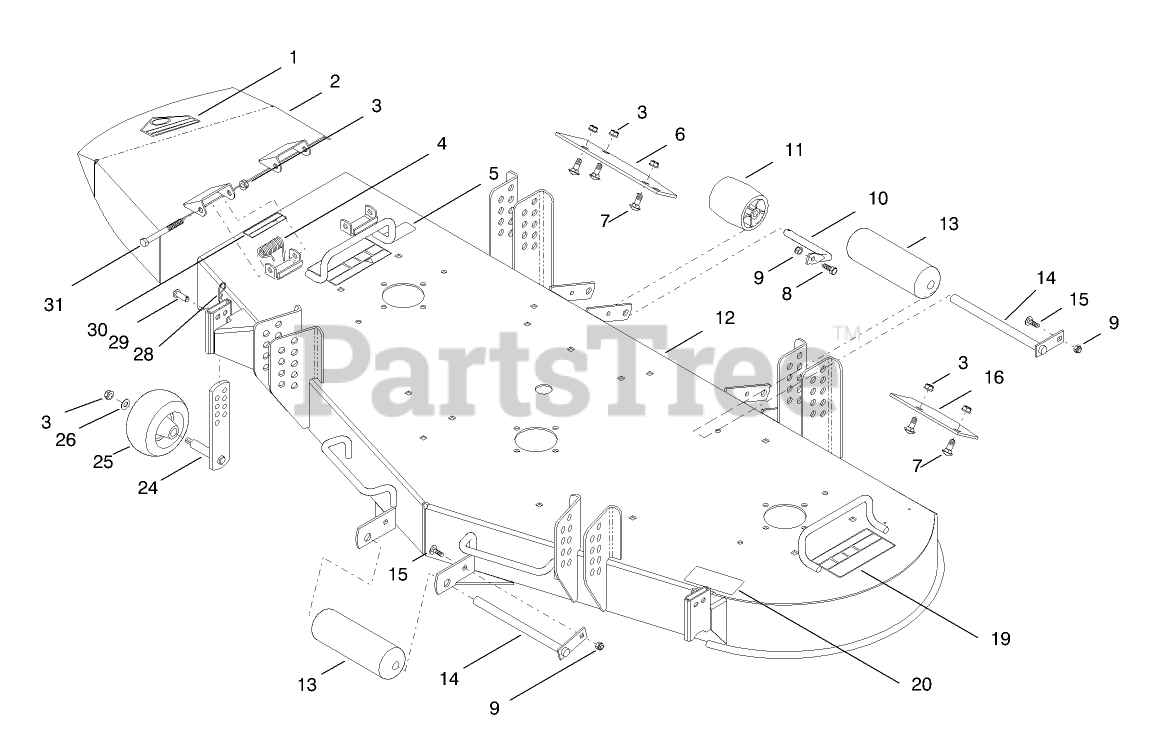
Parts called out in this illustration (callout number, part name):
1	DECAL-DANGER
2	Chute-ASM
2	CHUTE ASM
3	NUT-LOCK, NI
4	SPRING
6	PLATE-WEAR, RH
7	BOLT-CARR
8	SCREW-HH
9	NUT-LOCK, NI
10	ROLLER-SHAFT
11	Roller
12	60" DeckASM
12	DECK ASM
13	ROLLER-ANTI SCALP
14	ROLLER-SHAFT
15	BOLT-CARR
16	PLATE-WEAR, LH
19	DECAL-DANGER, THROWN OBJECT
20	DECAL - WHEEL ADJUSTMENT
24	GAGE-WHEEL
25	WHEEL-GAGE
26	WASHER-FLAT
28	PIN-HAIR
29	PIN-CLEVIS
30	DECAL-DANGER
31	SCREW-HH
